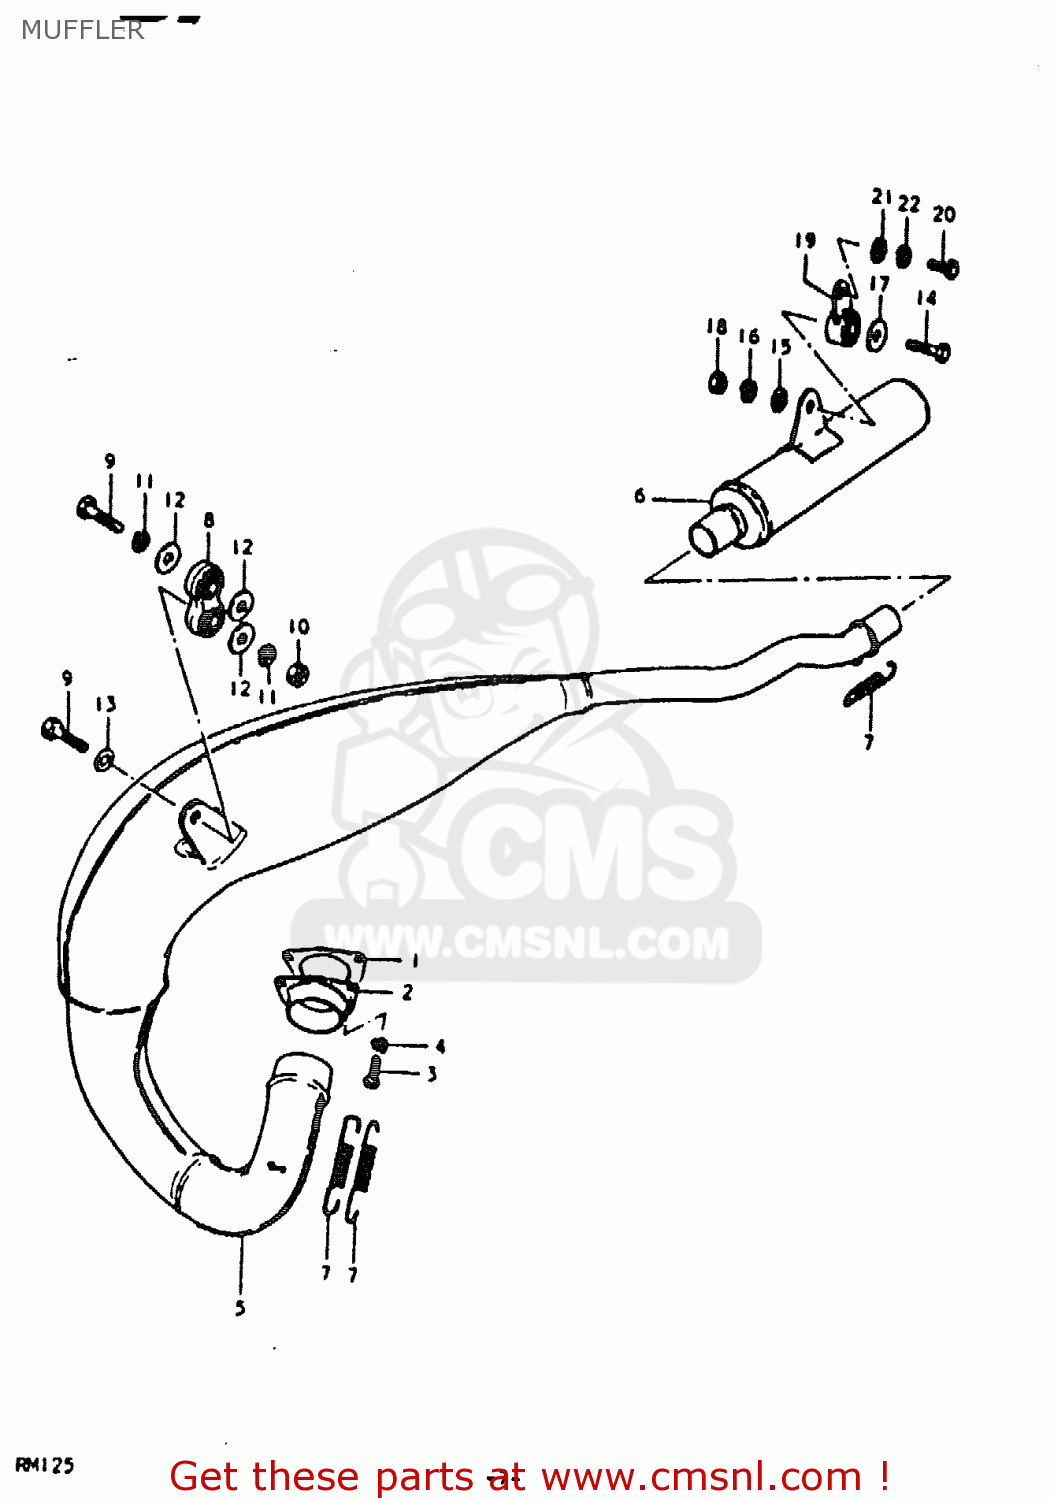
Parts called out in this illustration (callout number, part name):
1	GASKET,EXHAUST PIPE (MCA)
2	FLANGE,EXHAUST PIPE
3	SCREW
4	LOCK WASHER
5	BODY,MUFFLER
6	BODY,MUFFLER
7	SPRING
8	DAMPER,MUFFLER
9	BOLT
10	NUT
11	LOCK WASHER
12	WASHER
13	WASHER
14	BOLT (8X30)
15	WASHER
16	LOCK WASHER
17	WASHER (8.5X29X1.6)
18	NUT
19	DAMPER,MUFFLER SUPPORT
20	BOLT
21	WASHER
22	LOCK WASHER
